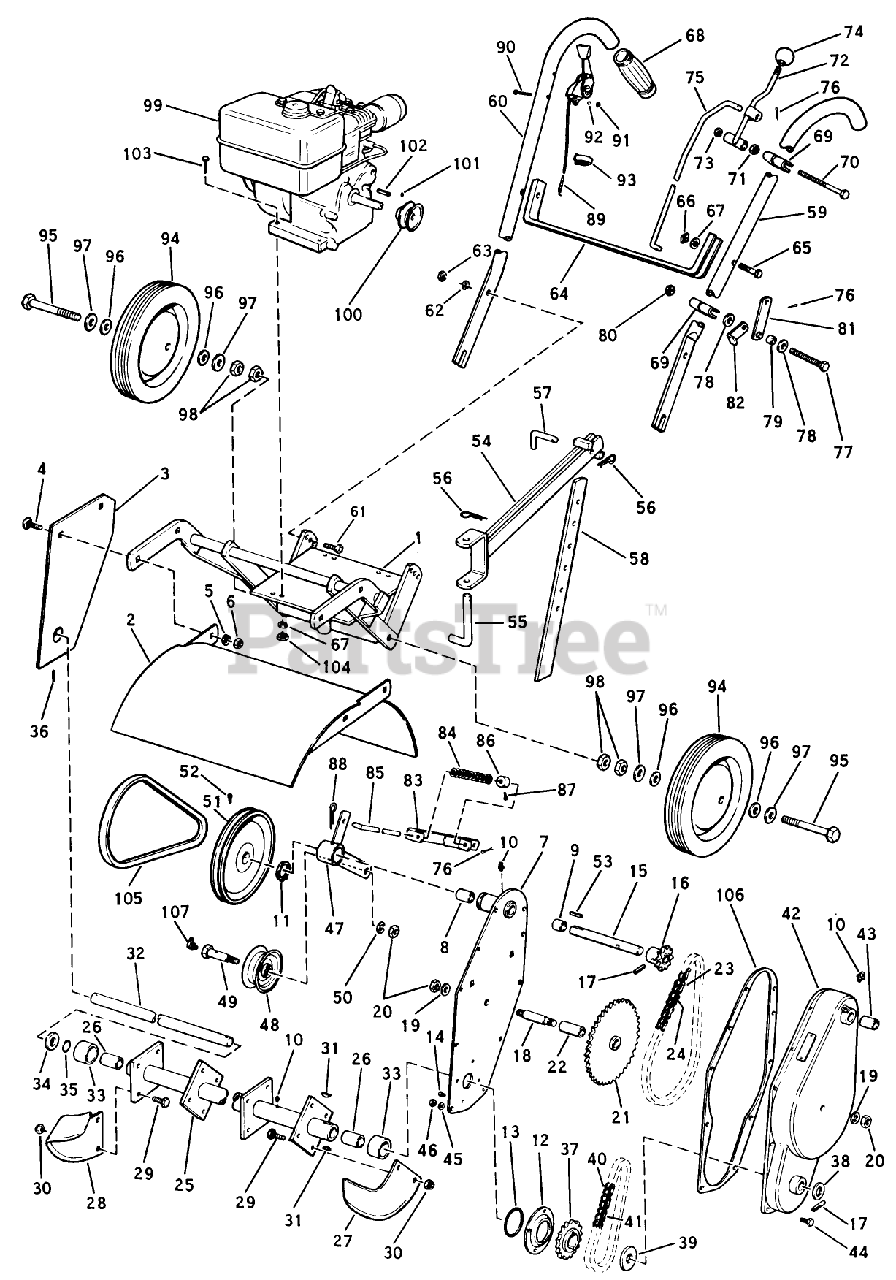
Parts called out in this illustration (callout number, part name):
1	Frame Assy.
2	Hood Assy.
3	Side Plate Assy.
4	Carriage Bolt 3/8-16 x 1 Lg.
5	Lockwasher
6	Hex Nut 3/8-16
7	Back Plate Assy.
8	Bushing
9	Bushing
10	Grease Fitting 1/4-28 St.
11	Snap Ring
12	Oil Seal Retainer
13	Ring (Neoprene)
15	Input Shaft
16	Input Sprocket Hub Assy.
17	Roll Pin 3/16 x 1-1/8
18	Intermediate Shaft
19	Lockwasher, Shakeproof
20	Jam Nut 1/2-20
21	Sprocket Cluster Assy
22	Bushing
23	Chain #41-1/2 Pitch, 55 Links
24	Connector Link
25	Rotor Tube Assy.
26	Bushing
27	Tine RH
28	Tine LH
29	Tine Bolt
30	Marsden Nut 3/8-24
31	Woodruff Key
32	Rotor Shaft
34	Thrust Washer
36	Roll Pin
37	Sprocket 18 Tooth
39	Thrust Washer
40	Chain #40-1/2 Pitch, 37 Links
41	Connector Link
42	Cover Assembly
43	Bushing
44	Capscrew 1/4-20 x 5/8 Lg.
45	Lockwasher, Shakeproof
46	Hex Nut 1/4-20
47	Idler Arm Assy.
48	Idler Pulley
49	Idler Pulley Shaft
50	Lockwasher
51	63559/GIL33166A 3 P
52	Set Screw 5/16-18
54	Beam Assy.
55	Anchor Pin
56	Spring Clip
57	Selector Pin
58	Depth Bar
59	Handle Bar Assy. LH
60	Handle Bar Assy. RH
61	Capscrew 3/8-16 NC x 1-1/4 Lg.
63	BOOM SWITCH
64	Bulb, Primer
65	Capscrew 5/16-18 NC x 1-1/2 Lg.
70	VALVE BRACKET ASSY
72	Control Lever Assy. LH
73	Retaining Ring
75	Control Rod LH
77	Capscrew 3/8-24 x 2-1/2 Lg.
81	Clutch Lever
82	Lever Stop
83	Spring Bracket Assy.
84	Control Spring
85	Transmission Control Rod
86	Set Collar
87	Set Screw
88	Spring Clip
89	Throttle Control Assembly
90	Machine Screw #8-32 x 1-1/2 Lg.
91	Hex Nut #8-32
92	Lockwasher
93	Cable Clip
94	Wheel Assy. 10 x 1.75
97	Washer 1/2 SAE
98	EXTENSION BOOM PIPE ASSY
99	Engine (BS)
101	Set Screw 5/16-18 NC x 5/16 Lg.
102	Key 3/16 Sq. x 1-1/8
103	Capscrew 5/16-18 NC x 1-1/2 Lg.
105	V Belt 37" A Section
106	Side Plate Gasket
107	Grease Fitting 1/4-28-90?
